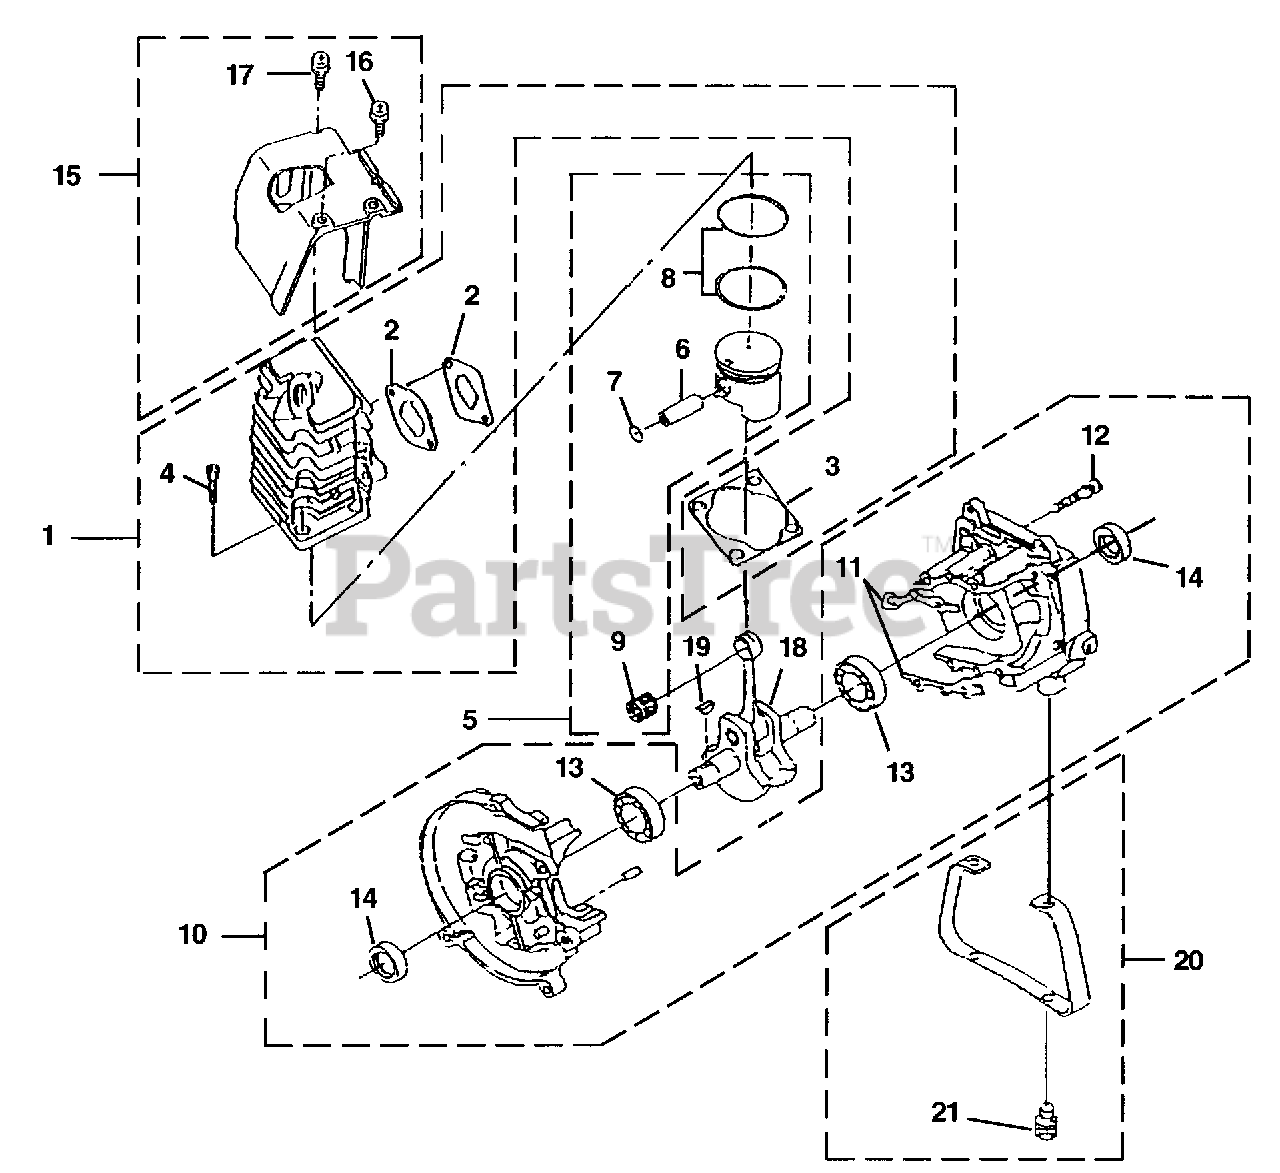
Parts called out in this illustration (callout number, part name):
1	CYLINDER ASSEMBLY
2	GASKET, MUFFLER
3	GASKET-Cylinder
4	SCREW-Socket Hd (M6 X 8)
5	PISTON ASSEMBLY
6	PIN - PISTON
7	RING - Retaining
8	RING - Piston
9	BEARING - Wrist Pin
10	CRANKCASE ASSEMBLY
11	GASKET-Crankcase
12	SCREW-Socket Hd (M5 x 30 SW)
13	BEARING, BALL
14	OIL SEAL
15	CYLINDER COVER
16	SCREW (M5 x 14 W SW)
17	SCREW (M5 X 20W SW)
18	CRANKSHAFT
19	KEY-Woodruff
20	ENGINE STAND
21	SCREW-Socket Hd (M6 x 14SW)
